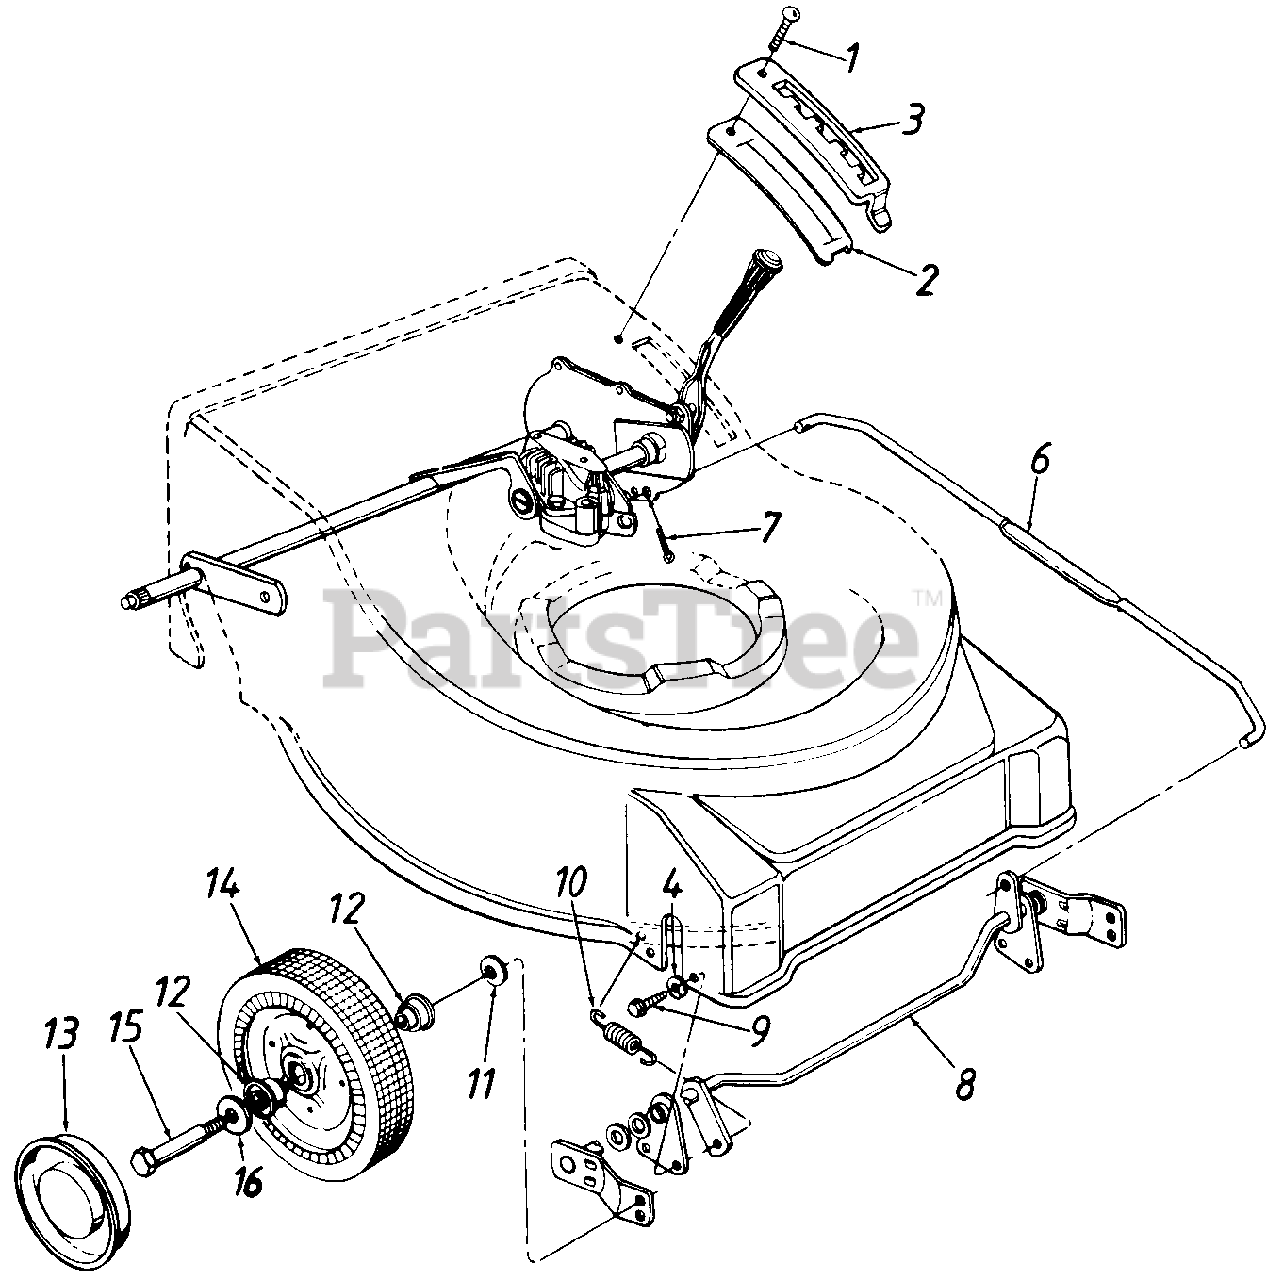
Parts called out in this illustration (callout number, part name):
1	Torx Mach. AB-Tap Scr. 1/4 X .62" Lg.
2	Height Adjustment Support
3	Height Adjustment Plate
4	L-Wash. 1/4" I.D.
6	Height Adj. Connecting Rod
7	Cotter Pin 3/32" Dia.
9	Hex L-Wash. Hd. AB-Tap Scr. 1/4 X .38" Lg.
10	Extension Spring 2.39" Lg.
11	Bell-Wash. .380" I.D. x .88" O.D.
12	Flange Ball Bearing 1/2" I.D.
13	Hub Cap
14	Wheel Ass'y. Comp.-Front
15	Shld. Bolt .498" Dia. x 1.45"
16	Fl-Wash. .531" I.D. x .93" O.D.
